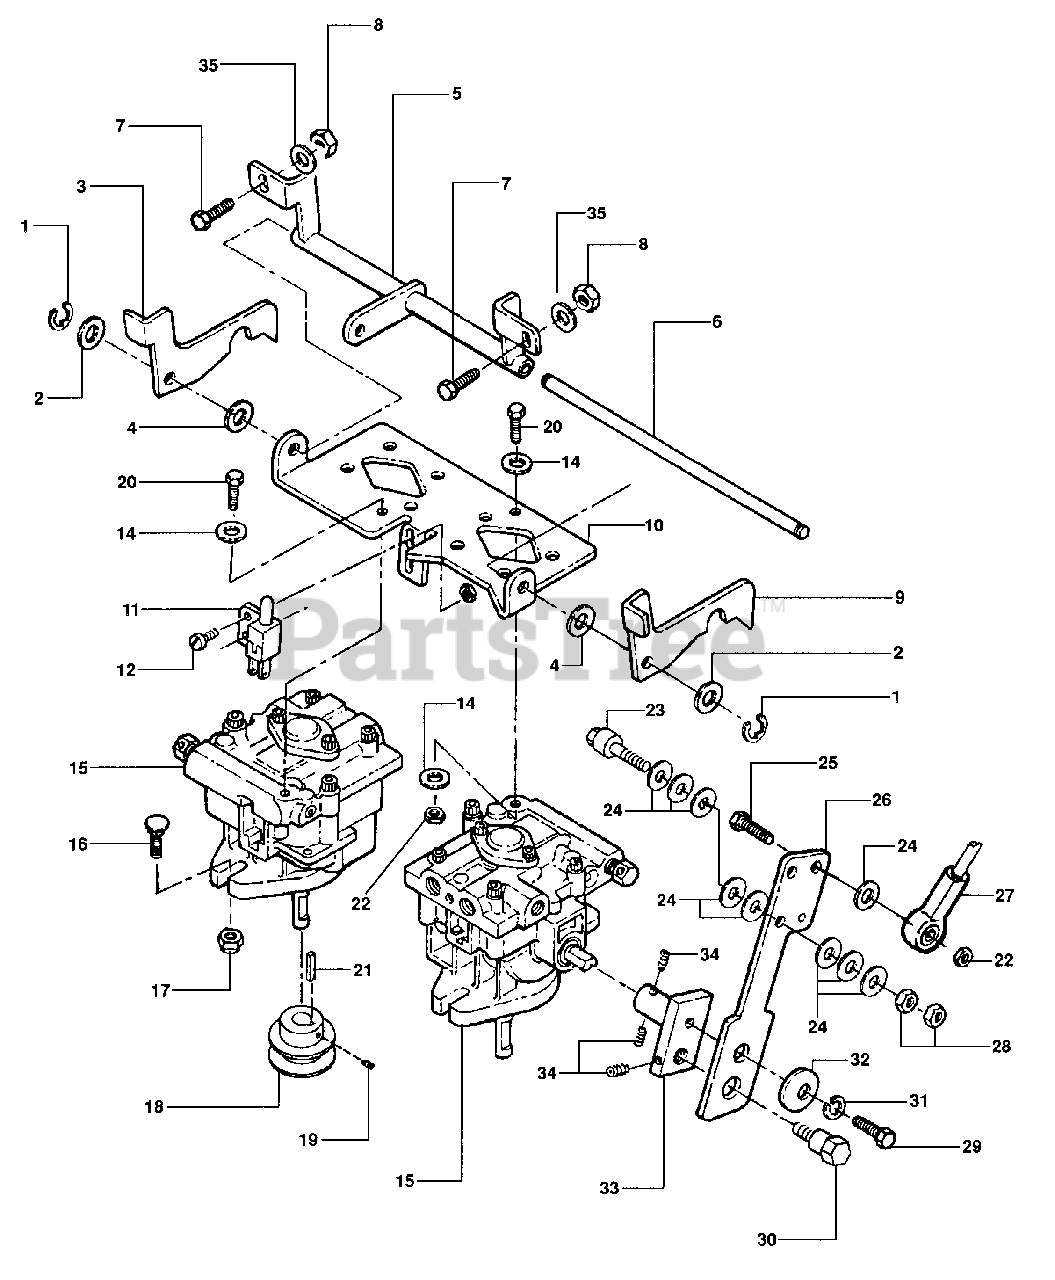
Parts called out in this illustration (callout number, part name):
1	"E" CLIP, 1/2"
2	BUSHING, 1/2"
3	NEUTRAL LOCK, Left Hand
4	WASHER, 1/2" Flat
5	WELDMENT, Neutral Tube
6	NEUTRAL ROD
7	SCREW, 1/4-20 X 1-1/2"
8	NUT, 1/4-20
9	NEUTRAL LOCK, Right Hand
10	SHELF PLATE
11	SWITCH
12	SCREW, #10-24 X 3/4"
14	WASHER, 5/16
15	PUMP, Hydraulic
16	BOLT, 3/8-16 X 1-1/4" Carriage
17	NUT, 3/8-16 Nyloc
18	PULLEY, 5.5"
19	SET SCREW, 5/16-18 X 3/8" Knurled Cup
20	BOLT, 5/16-18 X 2"
21	KEY, 5mm X 25mm
22	NUT, 5/16 Nyloc
23	ROLLER BOLT
24	WASHER, 5/16
25	SCREW, 5/15-18 X 1"
26	PUMP ARM
27	BALL JOINT LINKAGE, 5/16-24
28	NUT, 3/8-24 Nyloc
29	SCREW, 5/16-18 X 3/4"
30	ECCENTRIC
31	WASHER, 5/16 Lock
32	WASHER, 5/16 Cone
33	WELDMENT, Pump Mount
34	SET SCREW, 1/4-20 X 3/8" Nyloc Knurled Cup
35	WASHER 1/4 Flat
